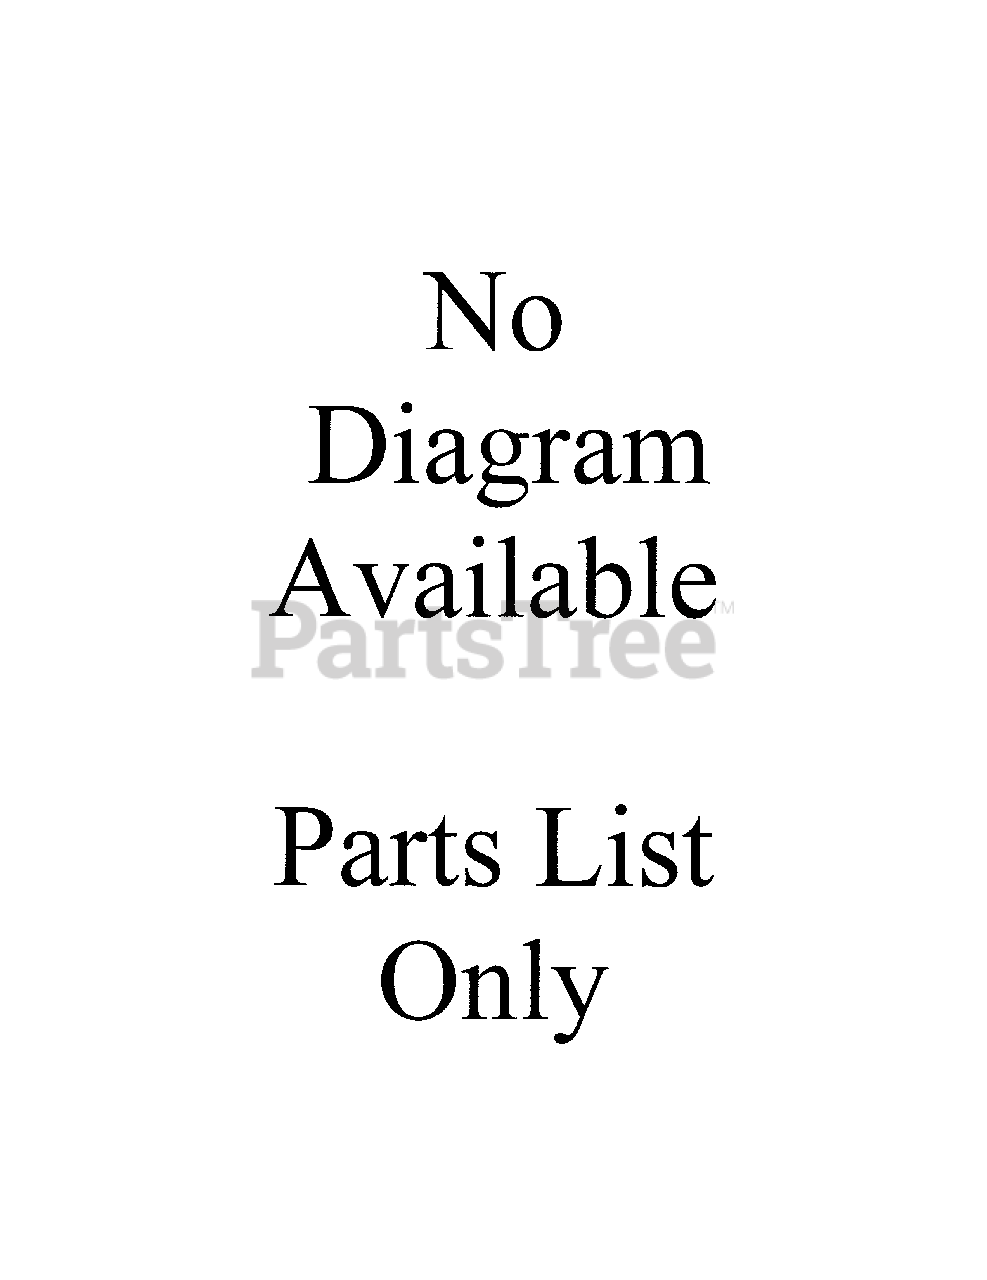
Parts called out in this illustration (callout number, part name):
1	Shaft Assembly
2	Pulley Support Assembly
3	Belt Guard
4	Pulley
5	Bearing w/Snap Ring
6	Spacer
7	V-Belt (Primary)
8	V-Belt(Secondary)
9	Pulley
10	Chute Control Assembly
11	Tube-Chute Control Support
12	Chute Control Support Assembly
13	Knob
14	Plug Button & Decal Assembly
15	Decal-Discharge Guide
16	Lift Support Arm
17	Lift Link Assembly
18	Lift Cable
19	Cable Clevis
20	Rear Frame Assembly
21	Channel-Frame Connector
22	Front Frame Assembly-R.H
23	Front Frame Assembly-L.H
24	Cap Screw
25	Cable Adjustment Bracket
26	Roller Mounting Plate-R.H
27	Roller Mounting Plate-L.H
28	Spring Adjustment Arm Assembly
29	Spring-Assist
30	Washer
31	Cable Roller
32	Spacer-Roller
33	Spacer-Gear Drive Tractor Only
34	Nut, Hex Cone Lock
35	Clevis Pin
36	Clevis Pin
37	Spring Clip
38	Spring Clip
39	Thread Forming Screw, Hex Hd
40	Thread Forming Screw, Hex Hd
41	Nut, Hex Center Lock
42	Thrust Washer
43	Cap Screw, Hex Hd
44	Cap Screw, Hex Hd
45	Cap Screw, Hex Hd
46	Cap Screw, Hex Hd
47	Cap Screw, Hex Hd
48	Nut, Hex Hd
49	Nut,HexConeLock
50	Washer, Spring Lock
51	Washer, Spring Lock
52	Washer, Flat
53	Washer, Flat SAE
54	Washer, Flat SAE
55	Key, Woodruff
56	Pin, Cotter
57	Pin, Roll
58	Set Screw, Hex Socket Hd. Cup Pt.
59	Bellcrank Assembly
